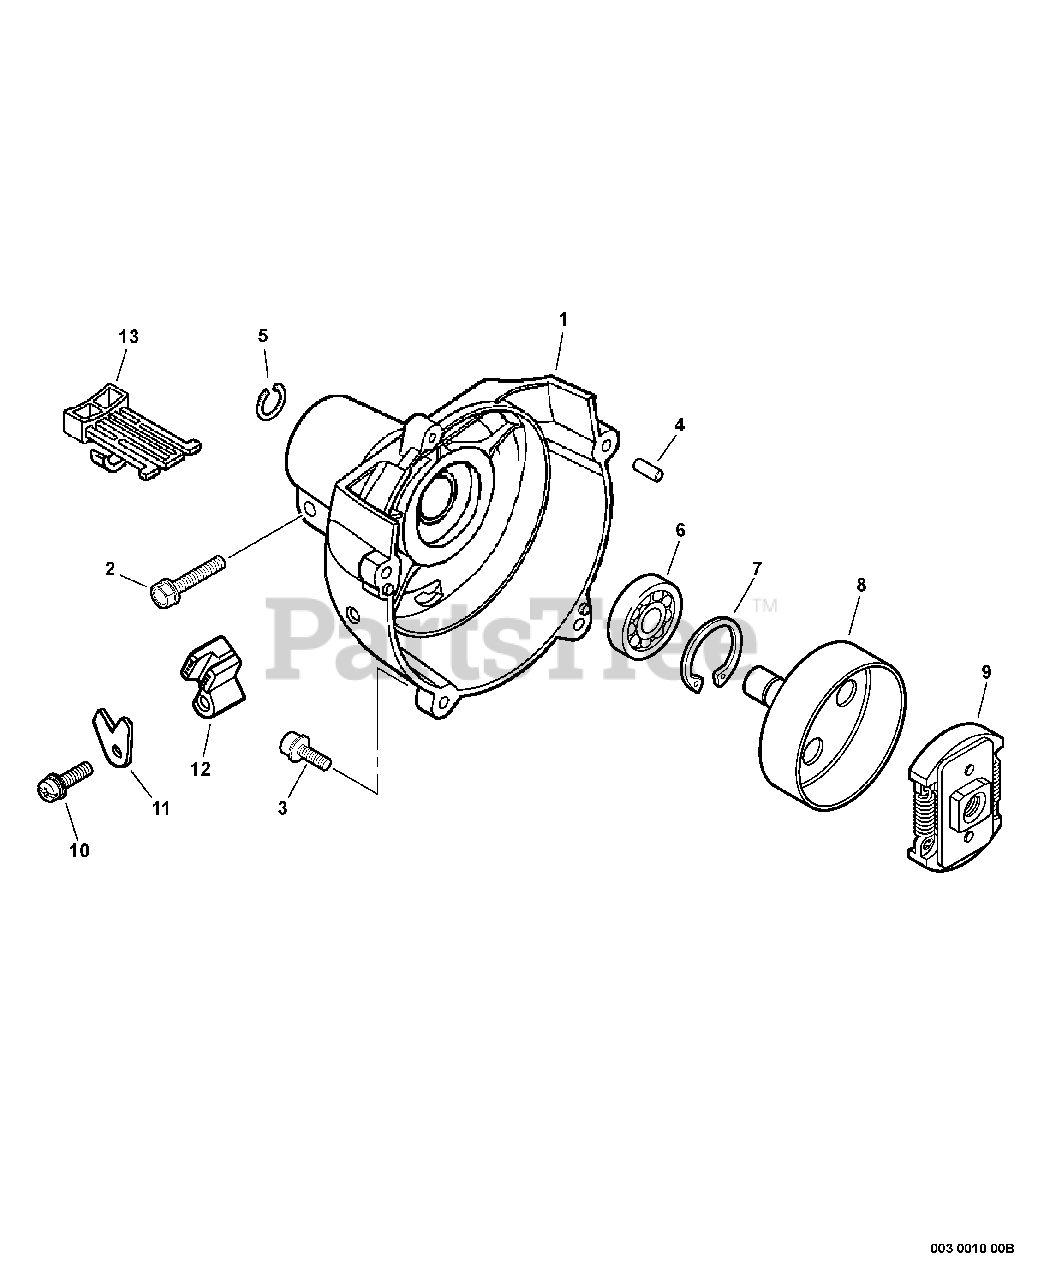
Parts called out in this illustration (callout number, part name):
1	COVER, FAN
2	SCREW - 5X28
3	SCREW - 4X16
4	PIN - LOCATING
5	RING, RETAINING - 12
6	BEARING, BALL - 6201
7	RING, RETAINING - 32
8	DRUM, CLUTCH
9	CLUTCH ASSY
10	SCREW - 4X18
11	COVER, CABLE HOLDER
12	HOLDER, CABLE
13	CLIP, CABLE
